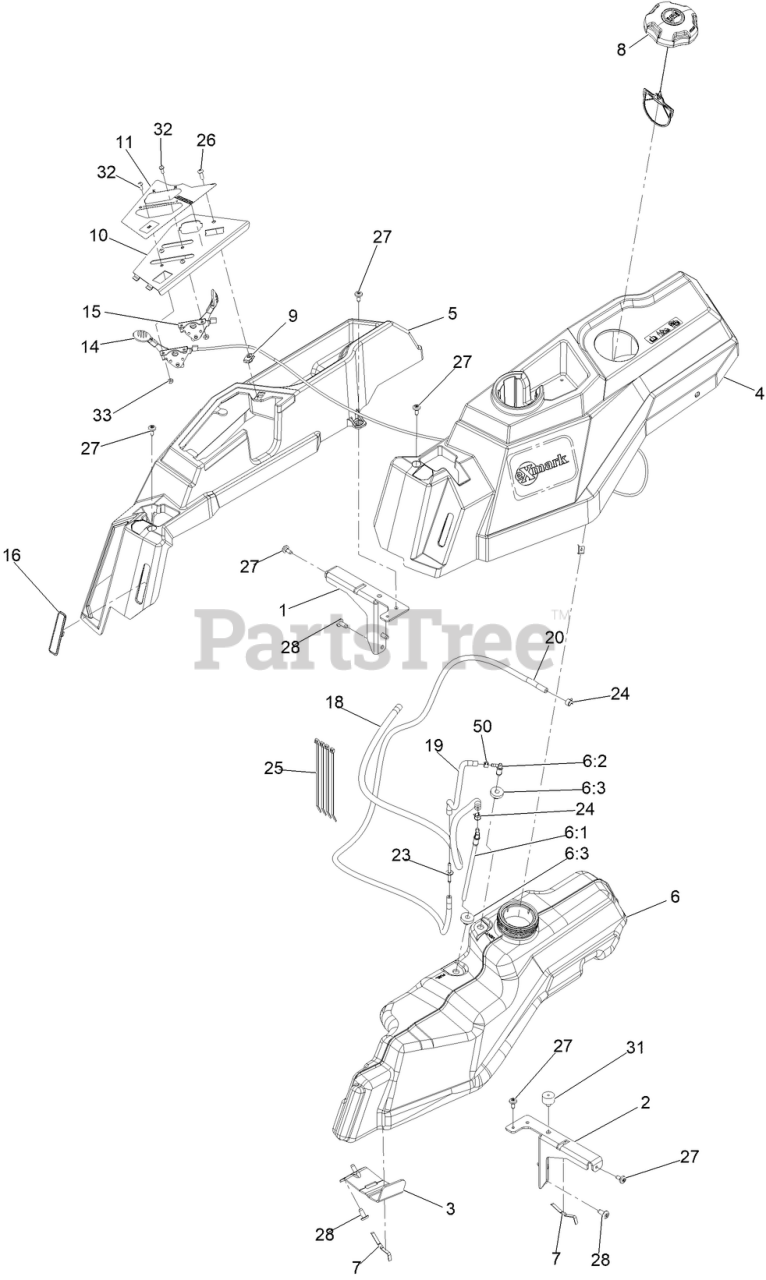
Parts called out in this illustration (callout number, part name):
1	SUPPORT-POD, RH
2	SUPPORT-POD, LH
3	SUPPORT-TANK, FUEL
4	POD- LH
5	POD- RH
6	TANK-FUEL ASM
6:1	Connector-Elbow, 90 DEG
6:2	Fitting-Elbow 90
6:3	BUSHING
7	SPRING
8	CAP-FUEL, RATCHETING
10	PANEL- CONTROL
11	DECAL-CONTROL PANEL
14	ASM,THROTTLE CABLE
15	CABLE-CONTROL, CHOKE
16	PLUG-SC
18	HOSE-FUEL
19	Hose-Fuel
20	Hose-Fuel (.188 X .406 X 40.00)
23	Adapter Orifice
24	CLAMP-HOSE
25	TIE-CABLE
26	SCREW-PRH
27	SCREW-SHOULDER
31	BUMPER-GROMMET
32	SCREW-PPH
33	NUT-LOCK, NI
50	CLAMP-HOSE
